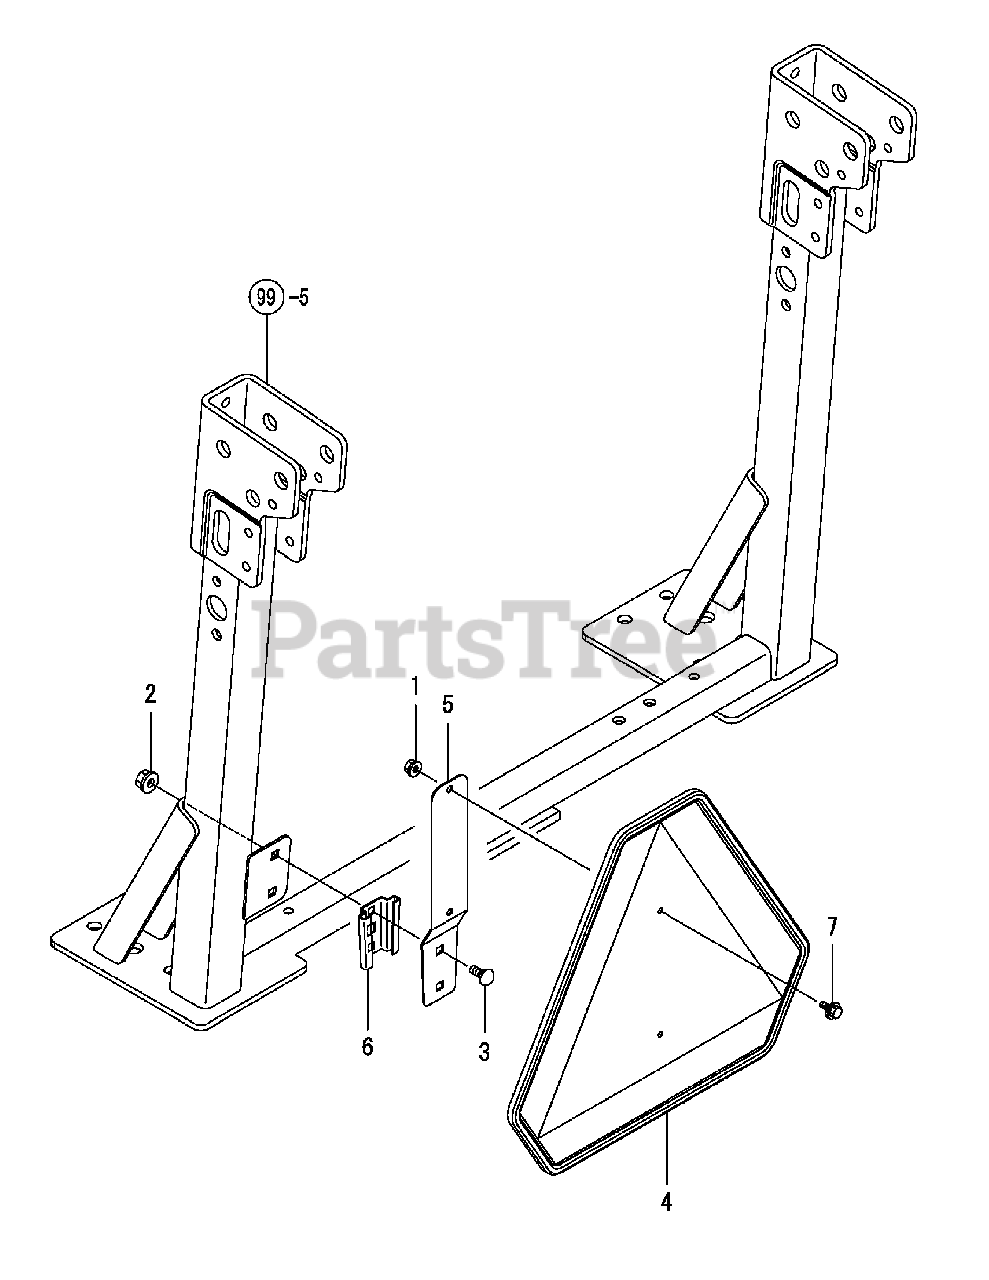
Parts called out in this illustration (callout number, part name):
1	Nut W/Washer 6
2	Nut W/Washer 8
4	Emblem,Smv Assembley
7	Bolt M 6X 16 Plated
